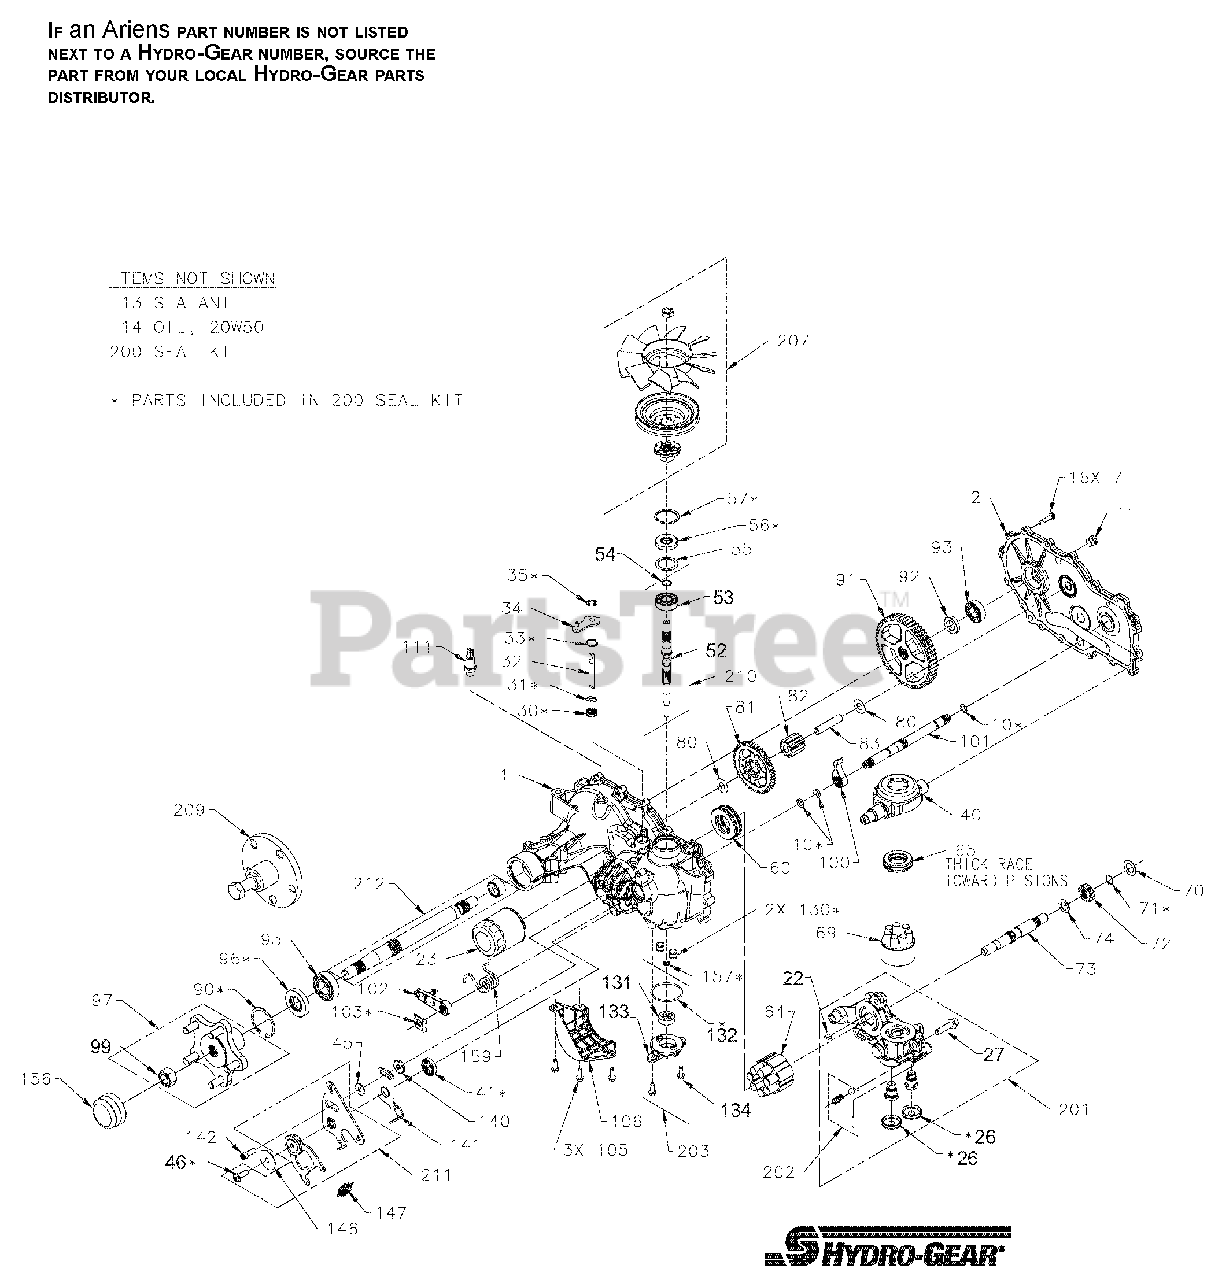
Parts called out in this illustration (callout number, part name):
1	Kit, Main Housing Right Hand
2	Kit, Side Housing, Right Hand
7	HFHCS 1/4-20 X 1.25"
11	PLUG, STEEL (WITH SEAL)
22	PLATE, BYPASS
23	Filter, Oil
30	SEAL, LIP .375X.75X.25
31	RING. RETAINING
32	Rod, Bypass
33	RING, RET .750
34	Arm, Bypass
35	RING, RTNG .
40	TRUNNION, SWASHPLATE
43	Puck, Friction
45	WASHER
46	TWHCS 5/16-24 X 1.00
52	Shaft, Input
53	BRG, BALL 17X40X12
54	Ring, Ret Wire .561 ID
55	WASHER 1.23X1.56X.04
57	RING, RET 1.56 INT
60	Bearing, Thrust
65	BEARING. THRUST 30 X 52 X 13
69	Assembly, Block, 7 Piston
70	WASHER .63X1.0X.05
71	RING, RET 62 EXT
72	Gear, 16T, Steel
73	Shaft, Motor
74	WASHER .71 X 1.16 X .04
80	WASHER .5X1.0X.032
83	JACK SHAFT (PIN)
90	RING, RETAINING
95	BEARING, BALL 25.4 X 52 X 15
96	SEAL, LIP
99	NUT, HEX, LOCK 3/4-16
103	Clip, Retaining
105	HFHCS 1/4-20X.75
106	Guard, Filter, RH
111	Fitting, Str 9/16-18 SAE .5 Barb
130	Tube, Connecting
131	GEROTOR
133	Cover, Charge Pump
134	HFHCS 1/4-20X.75
142	SHCS 5/16-24X1 PATCH
146	WASHER
147	Spring, Extension Rtn - 34 lbs
200	Kit, Seal ( * - parts included in this kit)
NS	SEALANT TUBE 10.1OZ.
NS	20W50 Oil
